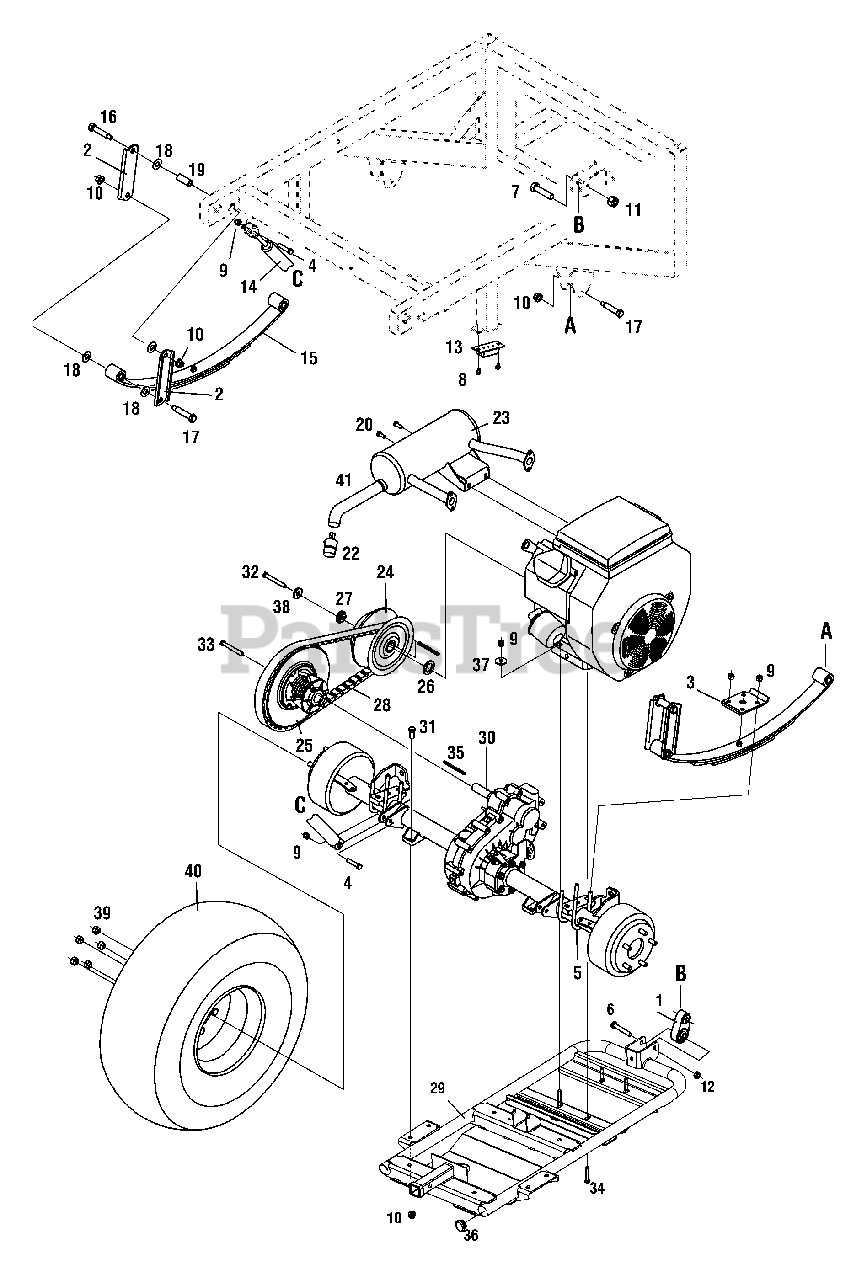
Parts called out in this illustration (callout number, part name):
1	Link Assembly
2	Plate, Shackle
3	Bracket, Spring Leaf
4	Hex Screw, 3/8-16 x 1.75
5	U-Bolt 3/8-16
6	Hex Screw, M12-1.75
7	Hex Screw, 5/8-11 x 2.5
8	Screw, Self Tapping 1/4-20
9	Locknut, Nylon, 3/8-16
10	Hexlock Nut
11	Hexlock Nut, Flange, 5/8 -11
12	Hexlock Nut, M12 x 1.75
13	Bumper, Suspension
14	Shock Absorber, 2.50 Stroke
15	Spring, Leaf 4 x 2
16	Shoulder Screw, .550 x 2.29
17	Shoulder Screw, .550 x 2.13
18	Bearing, .56 ID x 1.25 OD x .06
19	Bushing, .75 OD x .562 ID x 1.75 LG
20	Screw, M8 x 1.25:20
21	Valve, Oil Drain
22	Spark Arrestor
23	Muffler, Kohler
24	Clutch Assembly, Engine
25	Clutch Assembly, Transmission
26	Washer, Flat, 1.03 x 1.625 X .12
27	Spacer, .39 x 1.0
28	Belt, Cogged
31	Hex Screw, 7/16-20 x 1.0
32	Hex Screw,3/8-24 x 3.00
33	Hex Screw, 1/2-20 x 2.25
34	Hex Screw,3/8-16 x 2.00
35	Key, Square 1875 x 3.25
36	Plug, Tube
37	Washer, Flat, .510 x 1.00 x .125
38	Washer, Flat, .531 ID x 1.25 X 1.00 1
39	Lug Nut, 7/16-14
40	RH Wheel Assembly, 25 x 11 x 10
40	LH Wheel Assembly, 25 x 11 x 10
41	Muffler Pipe Extension
